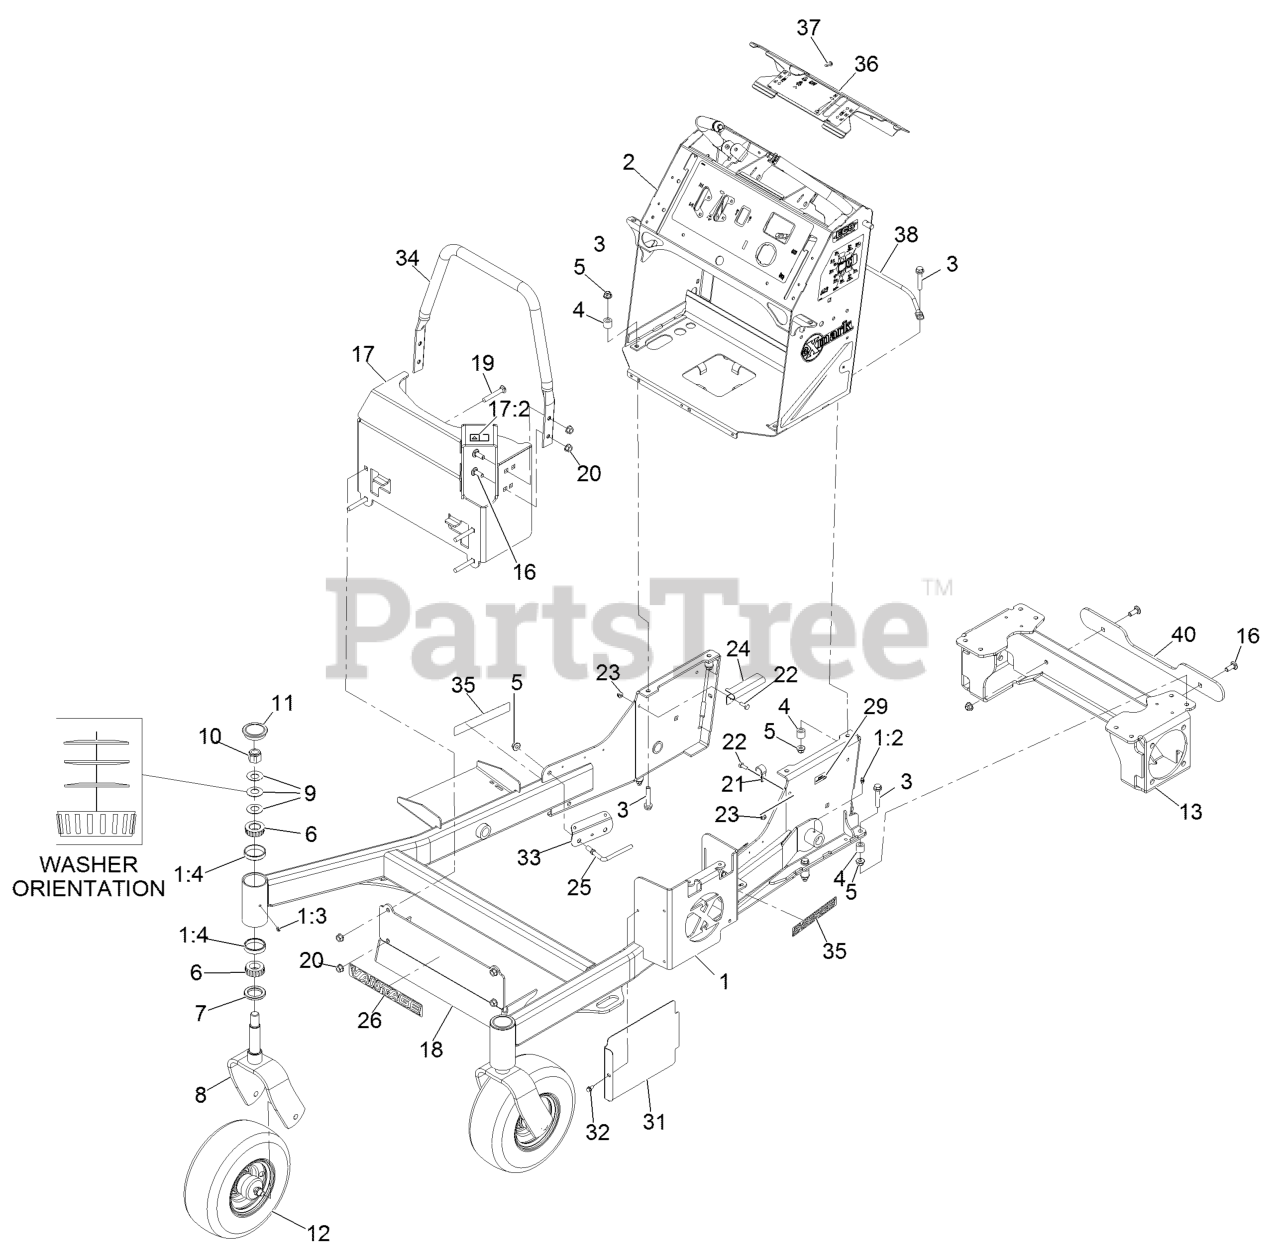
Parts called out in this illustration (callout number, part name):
1	FRONT FRAME ASM
1:2	FITTING-GREASE
1:4	CUP-BEARING
2	ASM, TOWER W/ DECALS
3	SCREW-HHF
5	NUT-HF, NI
6	Cone-Bearing Tapered Roller
7	SEAL-GREASE
8	FORK-CASTER
9	WASHER-BELLVILLE
10	NUT-LOCK, NI
11	CAP-GREASE
12	WHEEL/TIRE AND BEARING AS
13	MOTOR FRAME WELDMENT
16	SCREW-CARR
17	ASM, MUFFLER GUARD W/ DEC
17:2	DECAL-WARNING
18	PANEL-GUARD
19	SCREW-CARR
21	CLAMP-CABLE
22	SCREW-HH
24	BRACKET-HOSE, FUEL (DOUBL
25	GUIDE-HOSE, SUPPORT
26	DECAL-VANTAGE LOGO
29	Decal-Patent Ttco.Com
31	SHIELD-HEAT, TALL
32	SCREW-HWH
33	GUARD-HOSE
34	TUBE-GUARD
35	DECAL-X-SERIES
36	CONTROL PANEL W/DECALS
38	ROD, GUARD
40	PLATE, BUMPER SPACER
